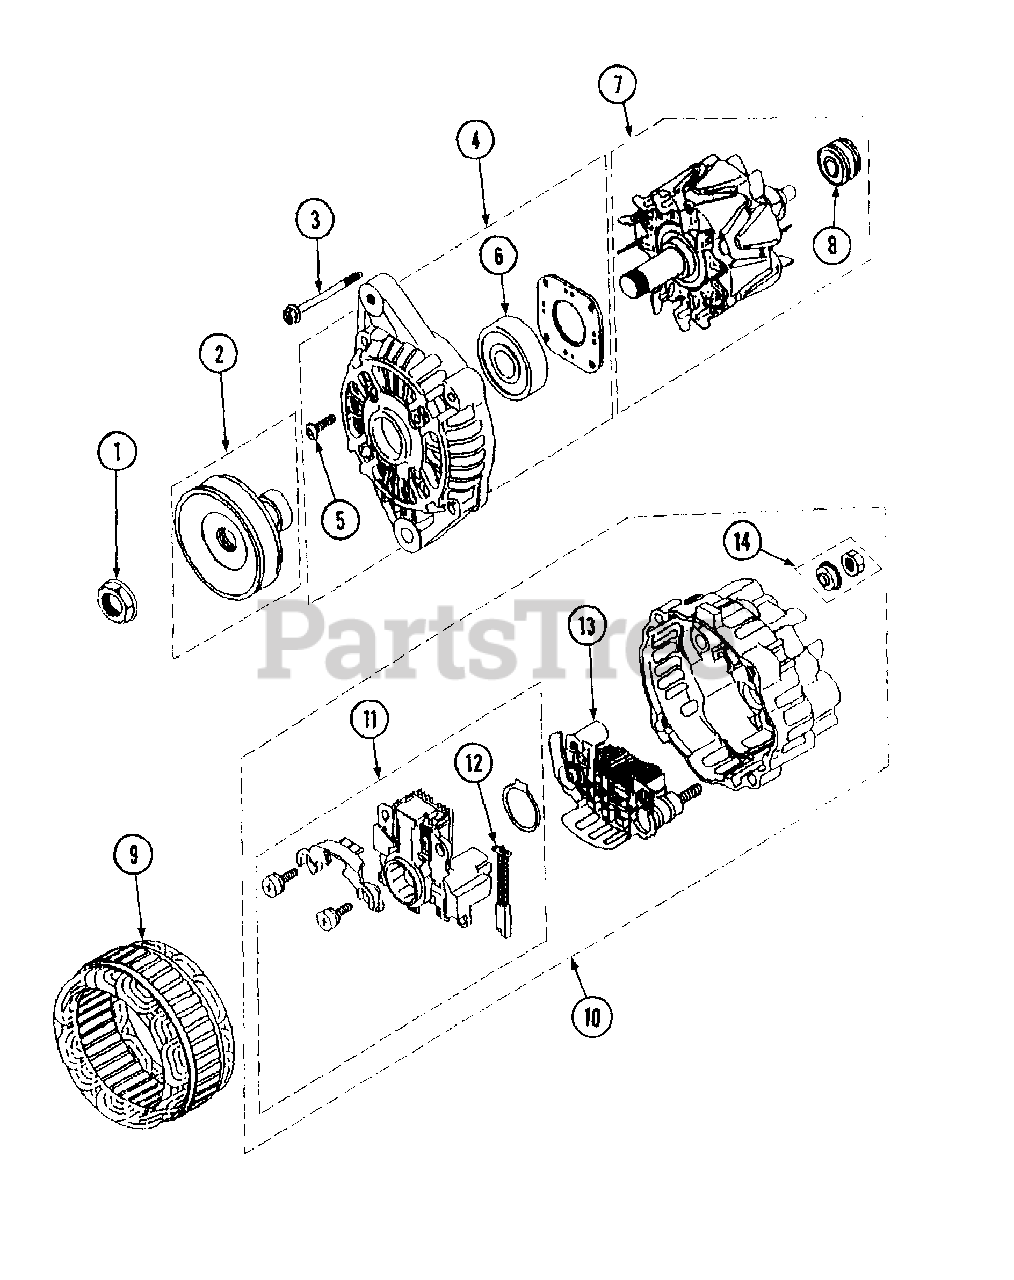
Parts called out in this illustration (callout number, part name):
2	Pulley Ass'y.
3	Bolt Set
4	Bracket Ass'y., Front
6	Bearing, Front
8	Bearing, Rear
9	Stator Ass'y.
10	Bracket Ass'y., Rear
11	Regulator Set
12	Brush
13	Rectifier Ass'y.
14	Nut Set
